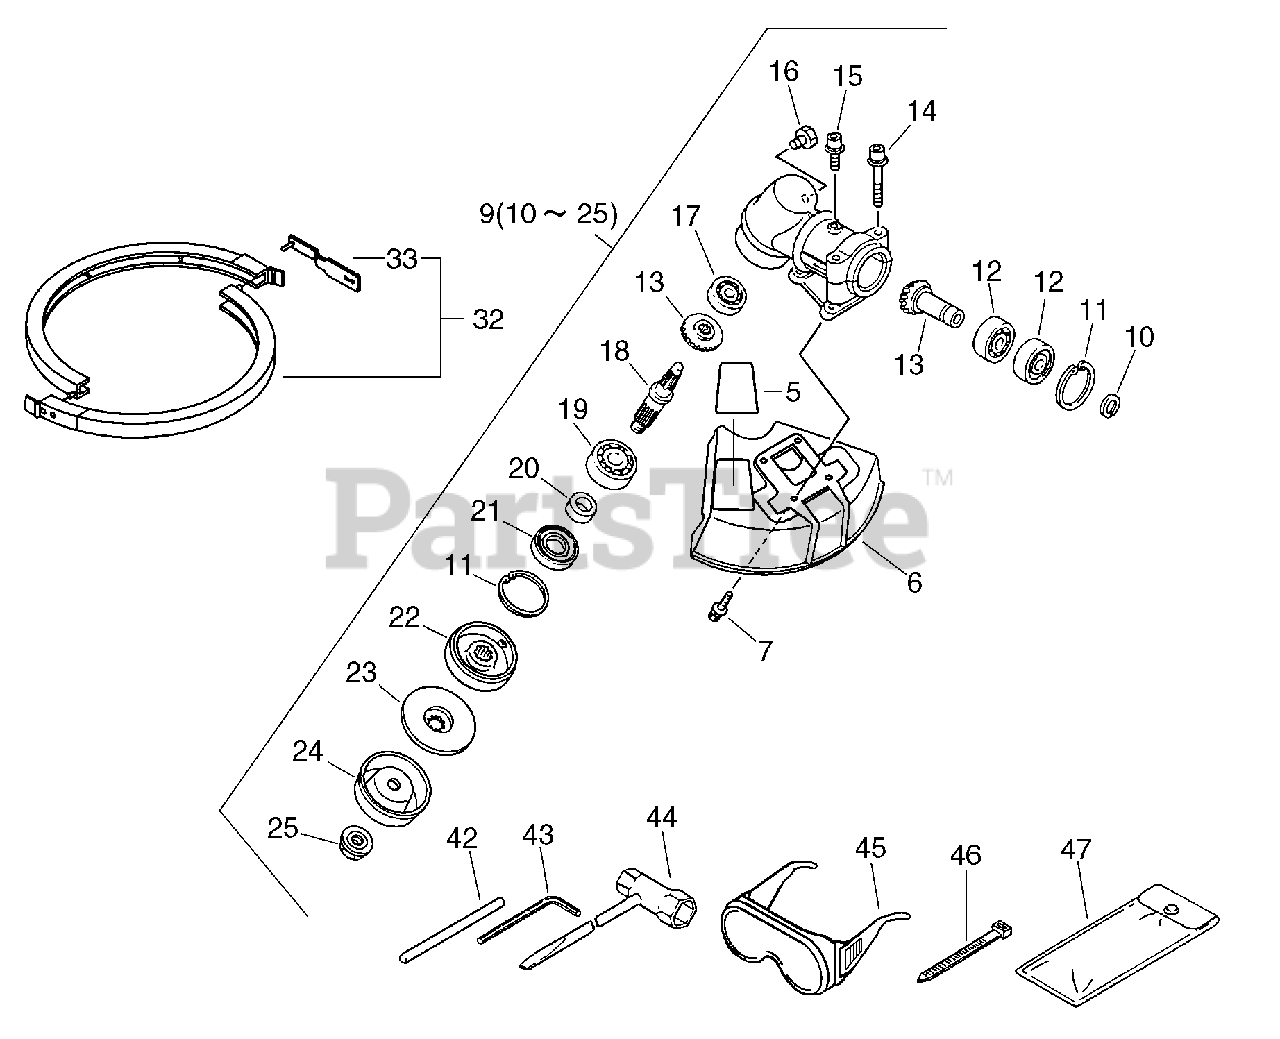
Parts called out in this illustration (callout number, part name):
5	LABEL, DANGER
6	SHIELD, DEBRIS
7	BOLT 5×20
9	GEAR CASE ASSY
10	RING, RETAINING 15
11	RING, SNAP 35
12	BEARING, BALL 6202
13	GEAR SET
14	BOLT M5×35
15	BOLT 5×14
16	BOLT M8×8
17	BEARING, BALL 6001
18	GEAR, SHAFT
19	BEARING, BALL 6202
21	SEAL, OIL
22	PLATE, ADAPTER - UPPER
25	NUT, LOCK
32	COVER, BLADE
42	TOOL, LOCKING 5×120 MM
43	WRENCH, ALLEN 4 MM
44	T-WRENCH
45	GLASSES, SAFETY
46	STRAP, TIE
47	BAG, TOOL
